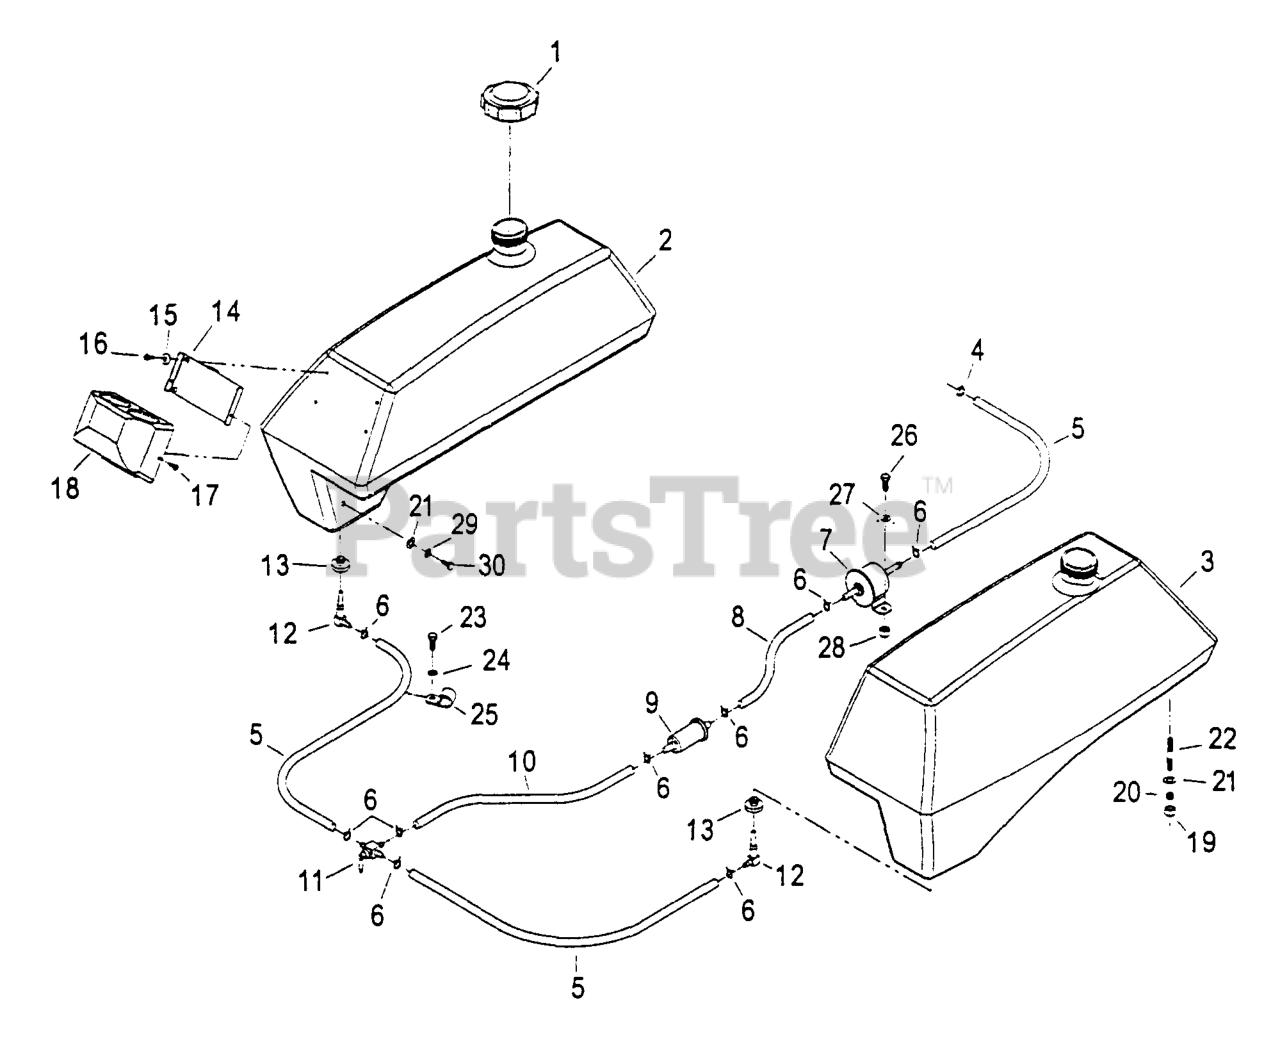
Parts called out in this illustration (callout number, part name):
1	CAP-FUEL
4	CLAMP-HOSE
5	HOSE-FUEL
7	Fuel Pump
8	HOSE-FUEL
9	Fuel Filter
10	HOSE-FUEL
11	VALVE-FUEL
12	ELBOW-TANK, FUEL
14	BRACKET,GAUGE MOUNT
15	WASHER-SPRING
18	COVER,GAUGES
20	SPRING-TANK, FUEL
22	STUD
24	WASHER-LOCK
25	CLIP-LOOM
29	WASHER-LOCK
